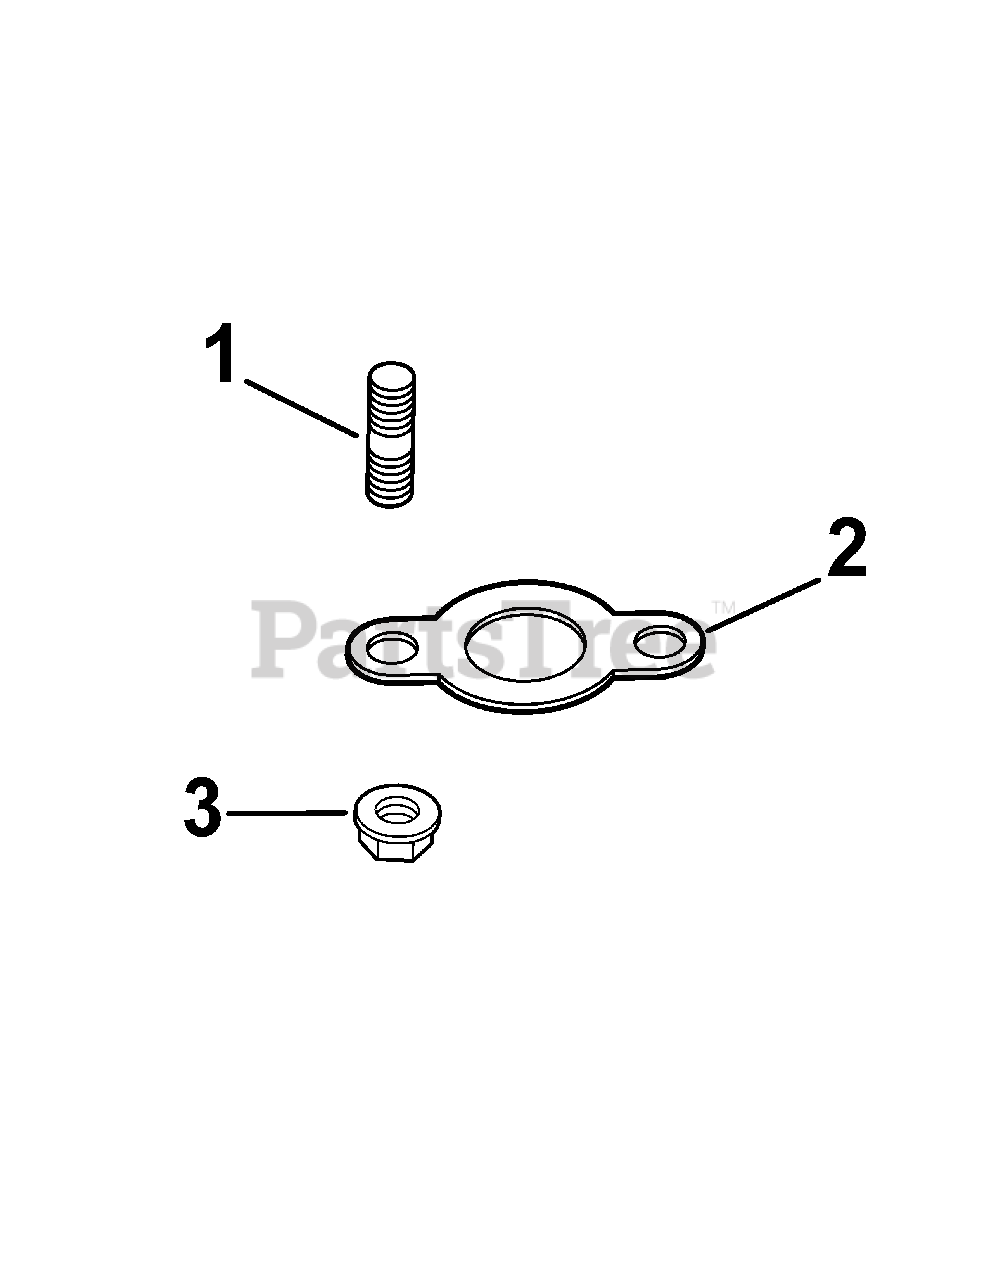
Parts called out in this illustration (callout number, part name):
1	Stud M8x1.25x33
2	Gasket, exhaust manifold
3	Nut, hex. flange M8x1.25
